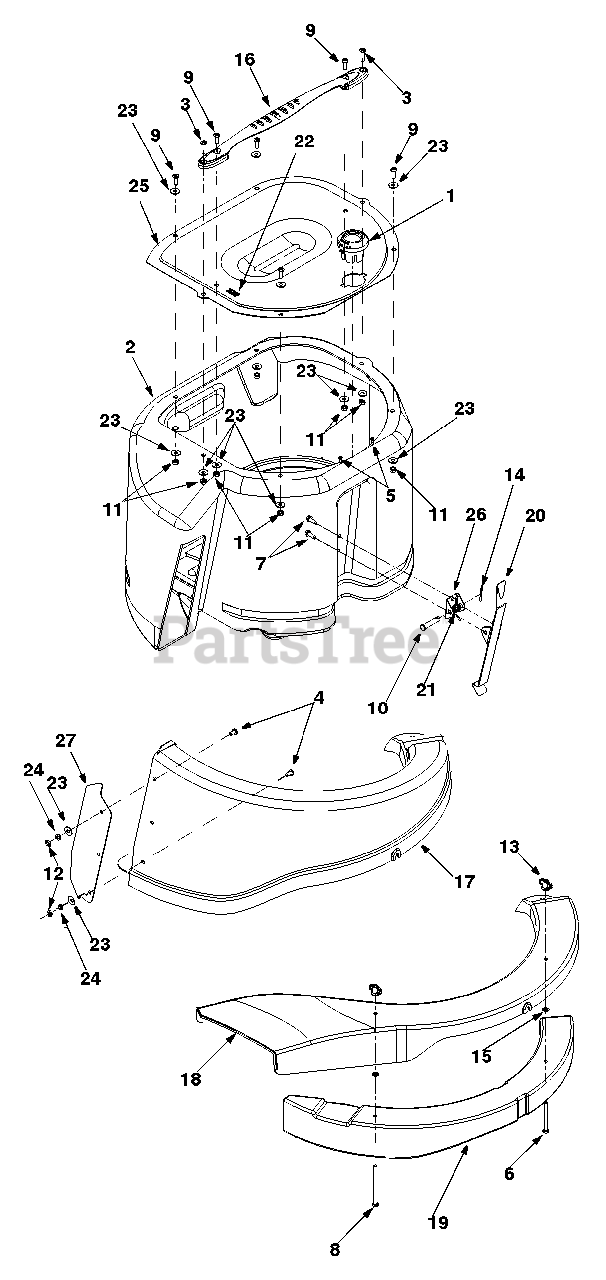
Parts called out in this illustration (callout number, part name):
1	Flow Indicator Assembly
2	Grass Bag Assembly
3	Machine Screw 1/4-20 x 1.0
4	Machine Screw 1/4-20 x 0.5"
5	Hex Screw #10-16 x 0.5"
6	Hex Screw 1/4-20 x 2.75"
7	Self-Tapping Screw 1/4-20 x 0.75"
8	Hex Screw 1/4-20 x 3.75"
9	Machine Screw 1/4-20 x 0.75"
10	Clevis Pin
11	Hex Sems Nut 1/4-20
12	Jam Nut
13	Wing Nut
14	Cotter Pin
15	Speed Nut
16	Bag Handle
17	Discharge Chute: Grass Bag
18	Side-Discharge Chute
19	Mulching Plug
20	Bag Release Lever
21	Torsion Spring
22	Clip Spring
23	Flat Washer
24	Lock Washer
